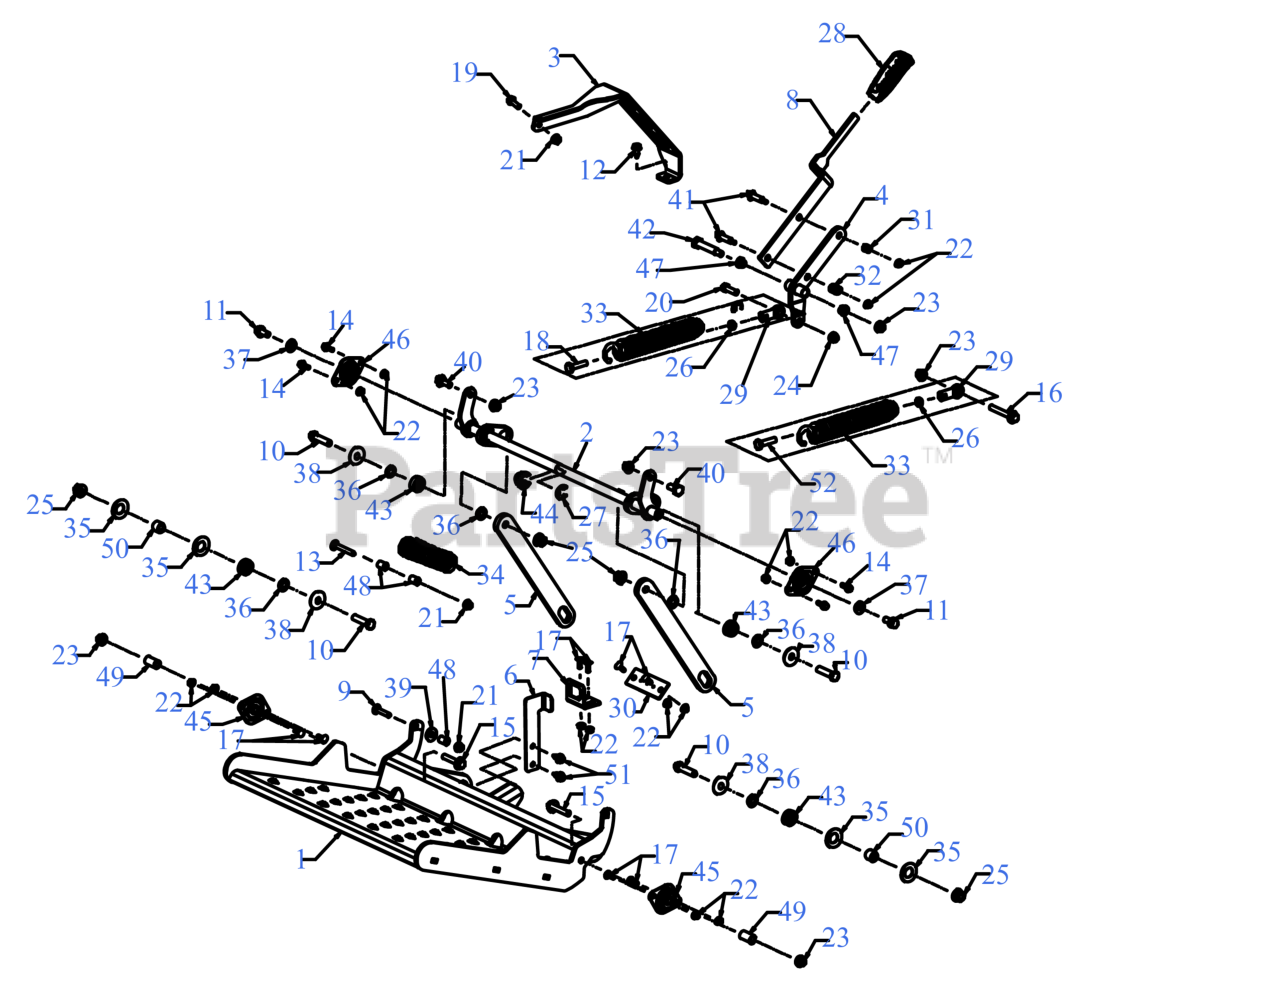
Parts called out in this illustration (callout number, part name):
1	PLATFORM ASSEMBLY
2	ROLLER LINK
3	ADJUSTMENT INDEX
4	ADJUSTMENT ARM
5	SUSPENSION LINK
6	SWITCH BRACKET
7	SWITCH BRACKET MOUNT
8	ADJUSTMENT SPRING LEVER
9	CARRIAGE BOLT 5/16-18 x 1.50
10	SCREW 7/16-20 x 1.75 GR 5
11	SCREW 3/8-16 x .875 GR5
12	SCREW 5/16-18 x .750
13	BOLT 5/16-18 x 2.50 GR1
14	SCREW 1/4-20 x .75 GR5
15	SCREW 3/8-16 x 2.0
16	SCREW 3/8-16 x 2.75 GR5
17	SCREW 1/4-20 x .75 GR5
18	SCREW 3/8-24 x 1.50 GR8
19	SCREW 5/16-18 x .875 GR5
20	SCREW 3/8-16 x 1.25 GR5
21	FLANGE LOCK NUT 5/16-18
22	FLANGE LOCK NUT
24	HEX LOCK NUT
25	FLANGE LOCK NUT
26	HEX JAM NUT 3/8X24
27	E-RING
29	ROD END 3/8 ID
30	SUSPENSION BUMPER
31	COMPRESSION SPRING
32	COMPRESSION SPRING
33	ADJUSTMENT SPRING
34	EXTENSION SPRING 1.478 x 5.729
35	FLAT WASHER .760ID X1.49OD x .06
36	FLAT WASHER
37	FLAT WASHER .385X.870X.090
38	FLAT WASHER
39	FLAT WASHER 344X1.00
40	SHOULDER SCREW
41	SHOULDER SCREW
42	SHOULDER SCREW .50 x 2.23 3/8-16
43	BALL BEARING
44	HEX FLANGE SPLIT BEARING
45	BALL BEARING
46	BALL BEARING
47	NYLINER BEARING
48	SLEEVE .33X.50X.75 LG
49	SPACER .380x.624x1.040
50	SPACER .465x.760x.550
51	SCREW 5/16-18 x .500
52	SCREW 3/8-24 x 1.75 GR5
